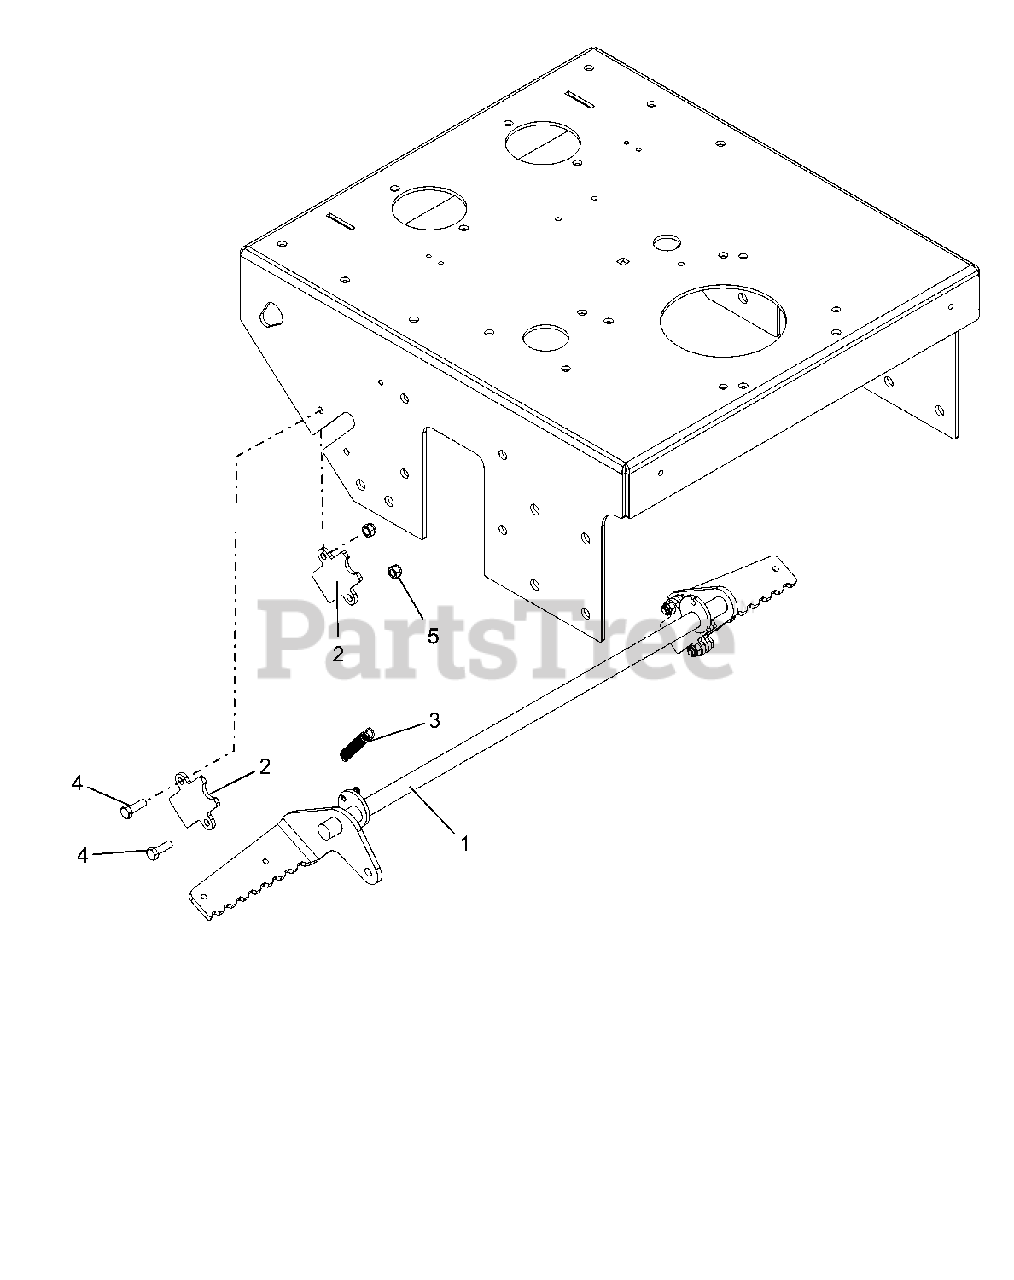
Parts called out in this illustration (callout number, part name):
1	WLDMT, BRAKE SYS FLOAT HYDRO-BLACK
2	SHOE, BRAKE SYSTEM FLOAT WALK-RED
3	SPRG, EXTENSION
4	BLT-HEX .31-18X1.00 GR5 YWZC
5	NUT-LK-NYL .312-18 YWZC
